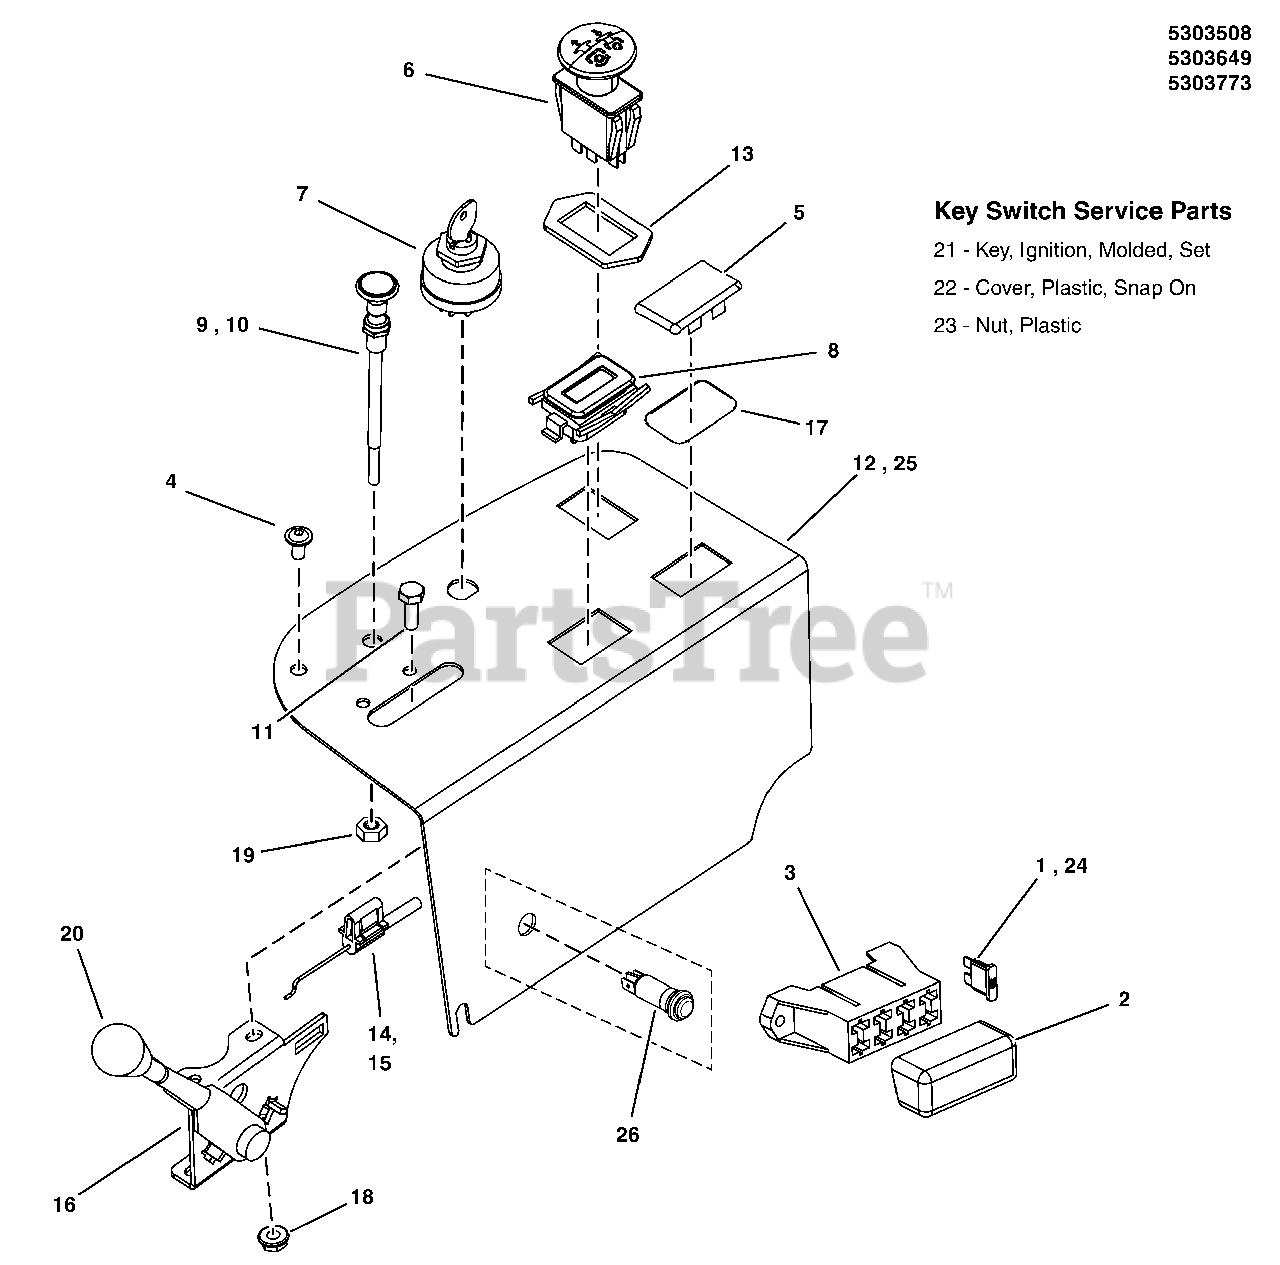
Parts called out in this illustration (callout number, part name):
1	FUSE, ATO, 20 AMP (SV)
2	COVER, VINYL FUSEBLOCK
3	FUSE, BLOCK
4	SCREW, ALLEN HEAD 1/4-20 X .500 ZINC PHOS
5	PLUG, Hole, Electric Lift (Hydro models only)
6	SWITCH, Blade Engage
7	SWITCH, IGNITION, 6 POST
8	HOUR METER, ASSEMBLE
9	CABLE, Choke
10	CABLE, CHOKE CONTROL, 51 (Z)
11	SCREW, #10-24 X 3/4", ROUND PHILLIPS
12	PANEL, CONTROL, IS2100Z - BLK
13	RING, SWITCH RETAINER, PTO
14	CABLE, THROTTLE, 42"
15	CABLE, THROTTLE, 47"
16	LEVER, THROTTLE CONTROL, HEAVY DUTY
17	O-RING, 7/8" ID X 1/16" W
18	NUT, Nylock, #10-24, GR2
19	NUT, 3/8 - 24 HEX
20	THROTTLE CONTROL HANDLE/KNOB
21	KEY, IGNITION MOLDED SET (SV)
22	COVER, PLASTIC, SNAP ON (SV)
23	NUT, PLASTIC (SV)
24	FUSE, ATO, 15 AMP (SV)
25	PANEL, CONTROL, IS2100Z - BLK
26	LIGHT, INDICATOR, PANEL, RED
